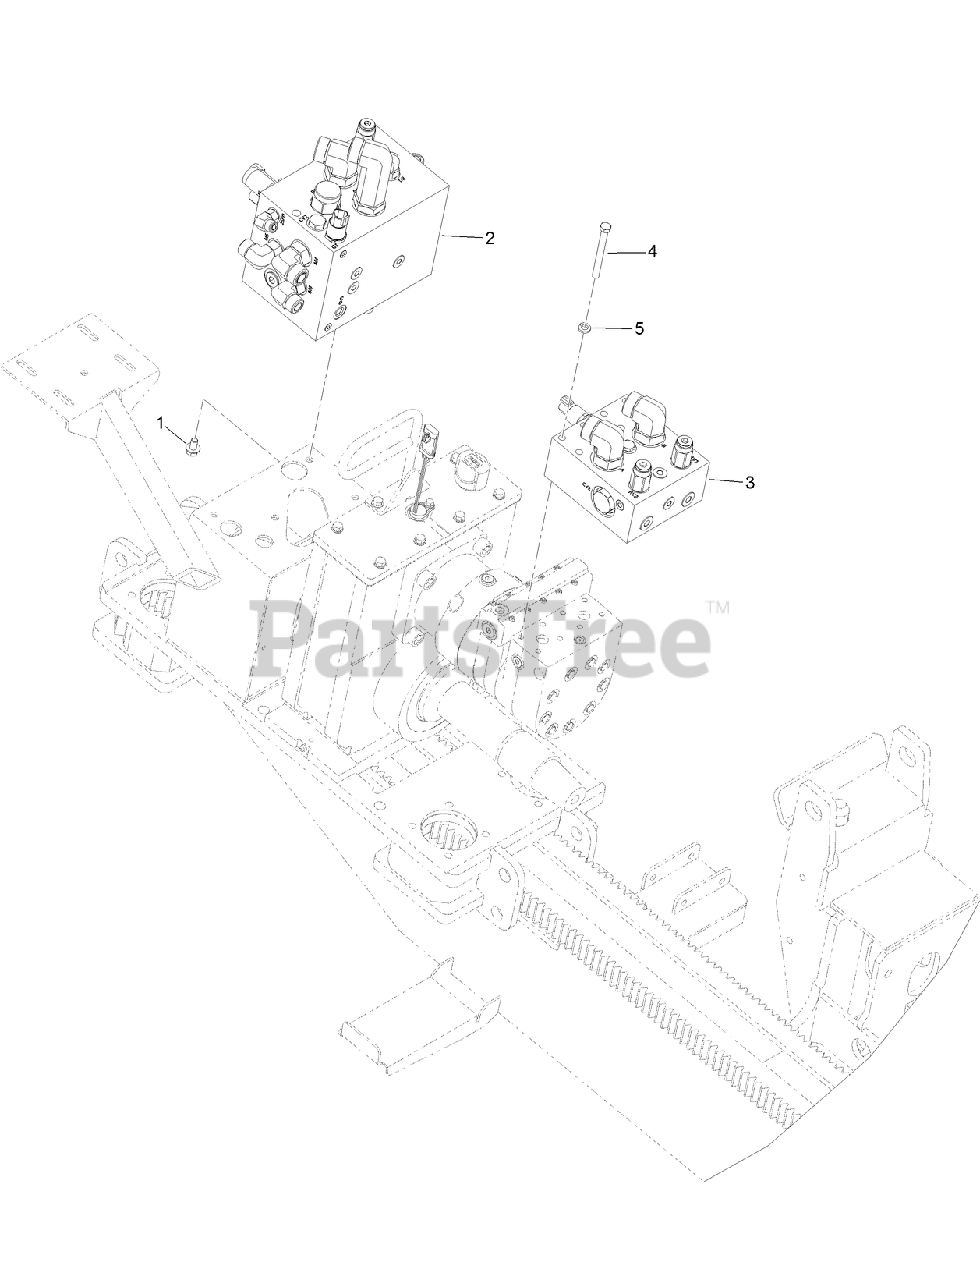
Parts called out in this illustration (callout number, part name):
1	SCREW-HHF
2	THRUST MANIFOLD ASM
3	ROTARY RELIEF MANIFOLD ASM
4	SCREW-HH
5	SCREW-HH
